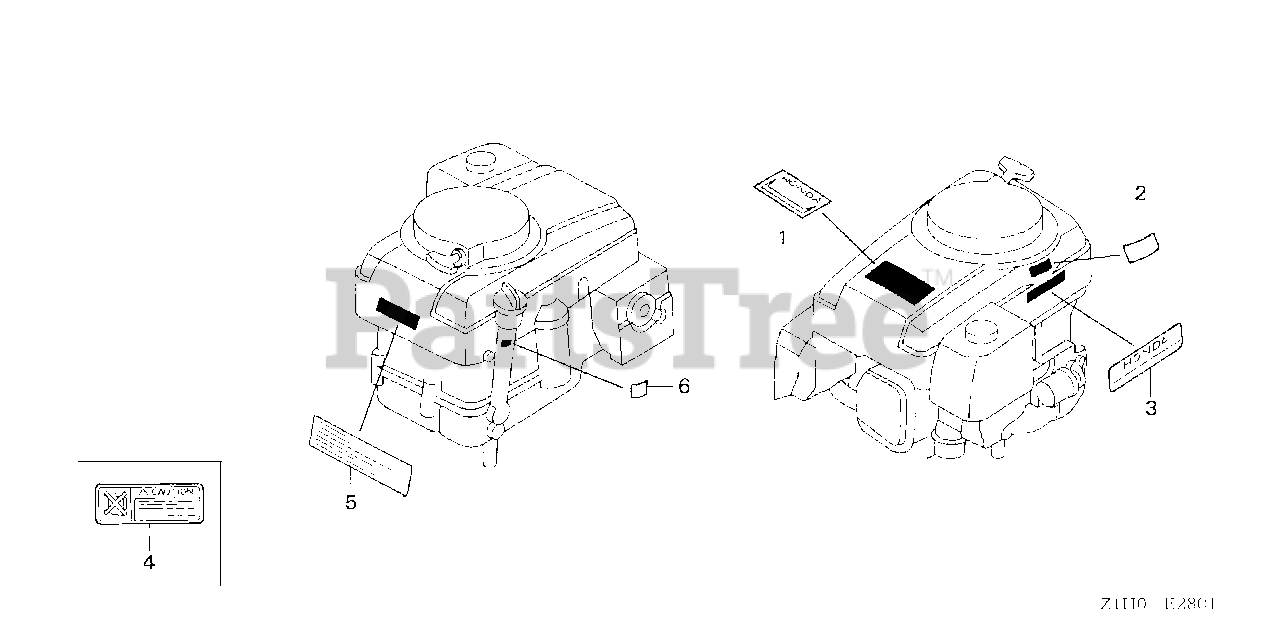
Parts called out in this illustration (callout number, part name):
1	EMBLEM, TOP COVER (11.0)
2	LABEL, FUEL CAUTION
3	LABEL, HONDA NAME
4	LABEL, MAINTENANCE CAUTION
5	LABEL, CAUTION
6	MARK, TYPE (DP23)
